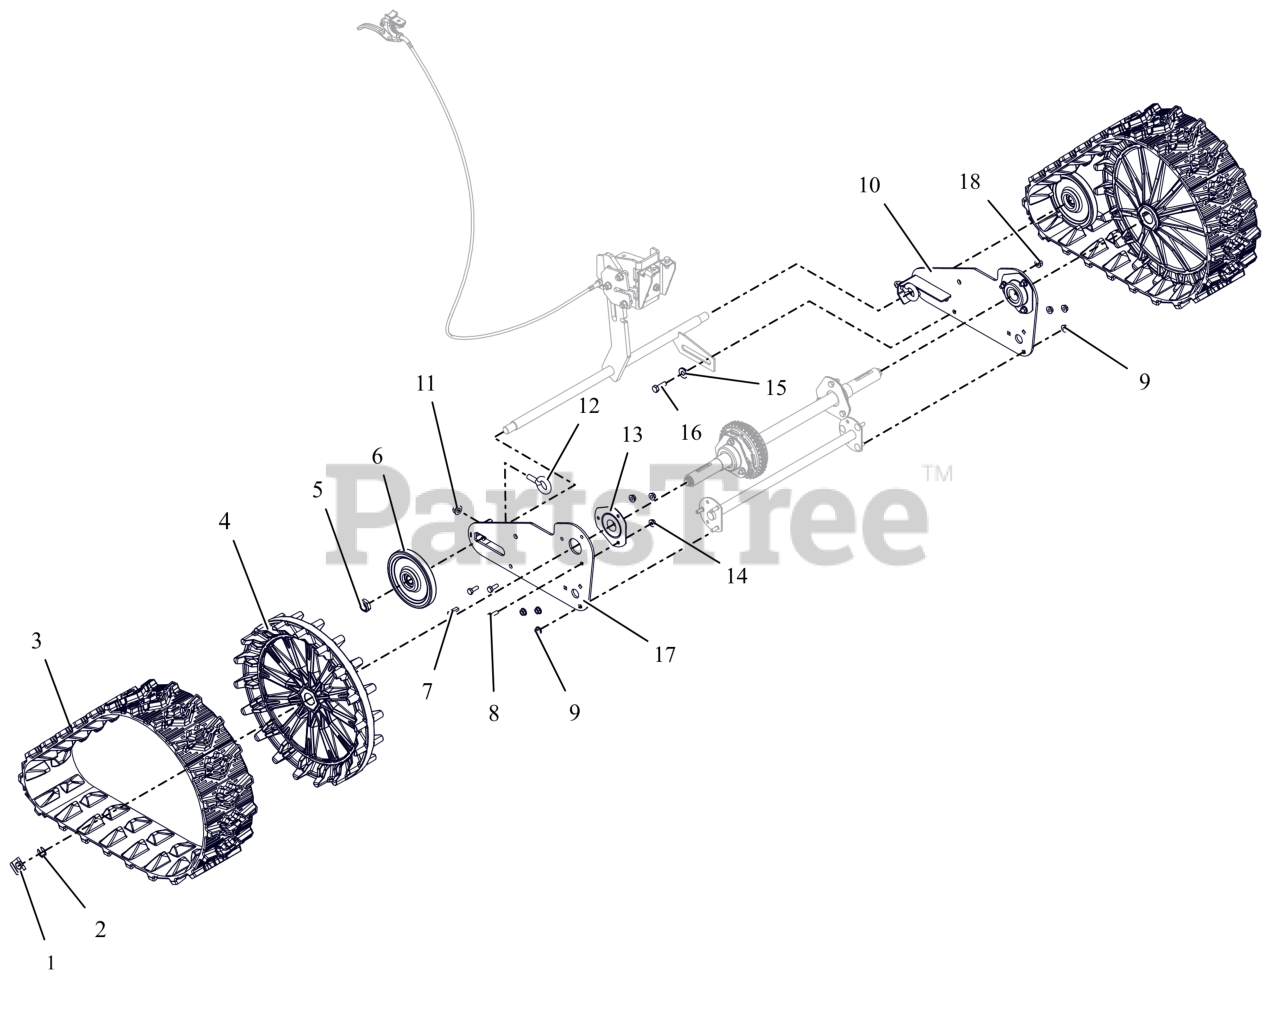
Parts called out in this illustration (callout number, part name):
1	CLIP, SNAP .625 DIA
2	RG-RTNG-EXT .625X.042
3	TRACK, RUBBER - 22 PITCHES
4	SPROCKET, LARGE TRACK DRIVE
5	NUT, NYL LK .625-18 ZCC
6	WHEEL, BOGIE - SINGLE BEARING
7	KEY-RECT .25X.188X1.00
8	BLT, HEX .25-20X.75 G5 ZCC
9	NUT-LK-TOP-FLG .250-20 GF ZCC
10	PLATE, SIDE-BWT LH WLDMT
11	NUT-LK-CTR-FLG .375-16 GF ZCC
12	BLT-EYE .375-16X.880 YWZC
13	BRG-FLG 1.003/1.000 3 BOLT
14	NUT-LK-TOP-FLG .250-20 GF ZCC
15	BSHG-FLG .325X.499X.3X.875
16	BLT,HEX .31-18X1.00 G5 ZCC
17	PLATE, SIDE-BWT RH WLDMT
18	NUT-LK-TOP-FLG .312-18 GF ZCC
